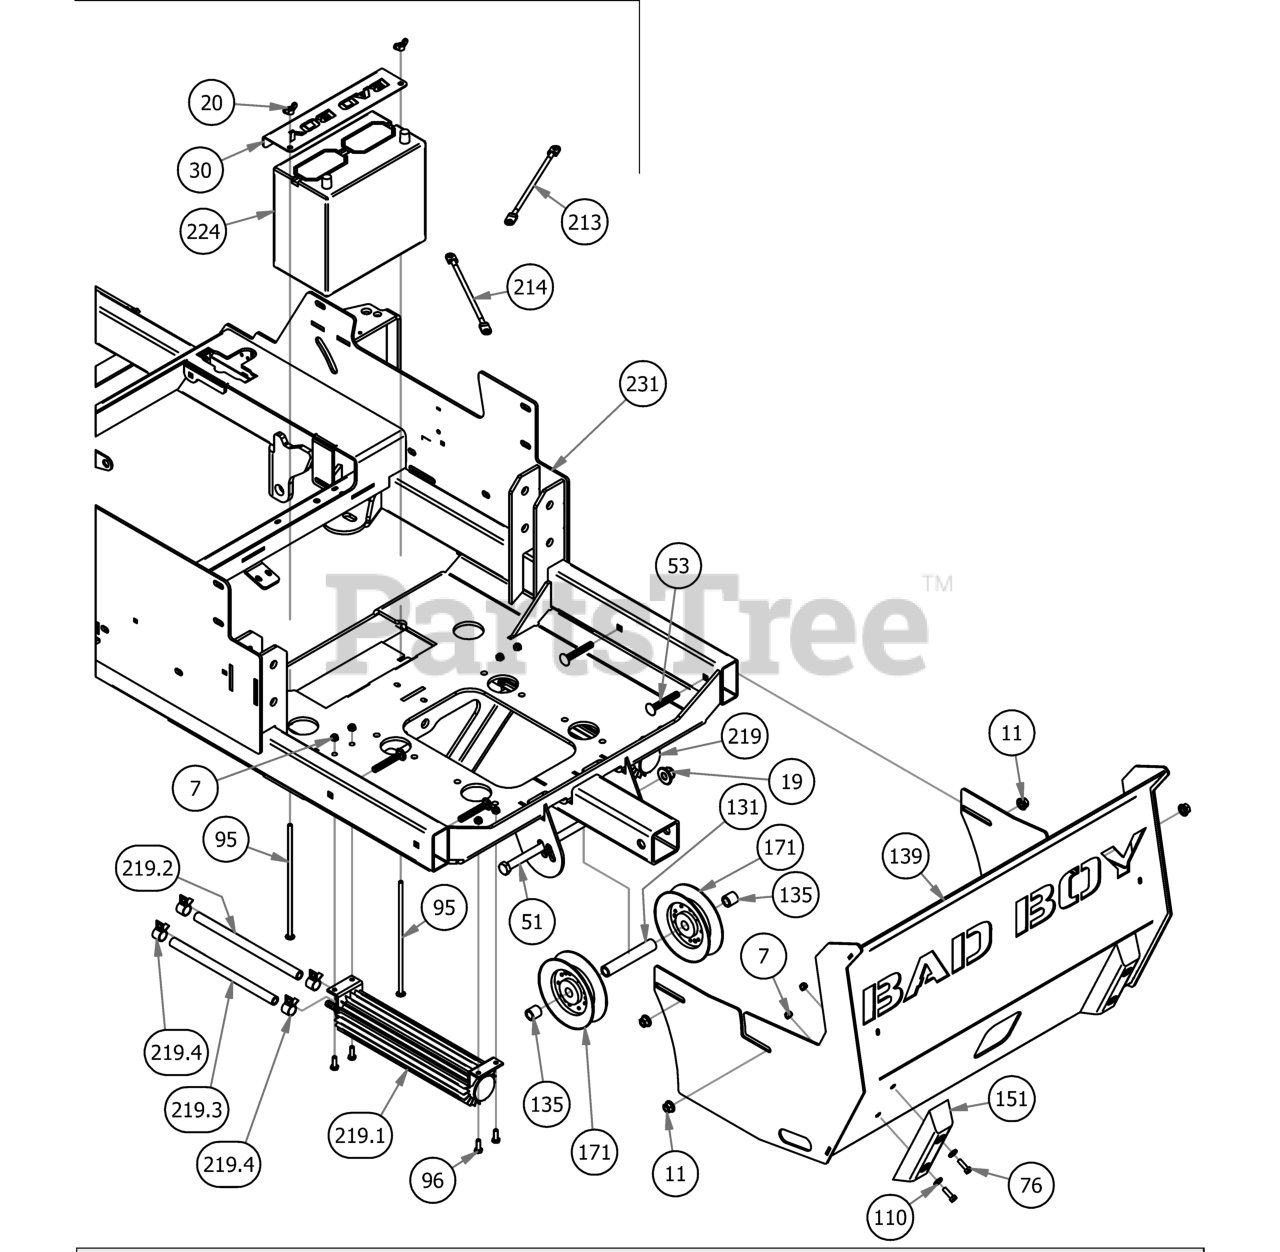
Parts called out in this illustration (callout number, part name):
7	1/4-20 Hex flang lock nut
11	3/8-16 NYLON INSERT FLANGE LOCKNUT (GR.F) ZINC
19	1/2-13 NYLON INSERT FLANGE LOCKNUT ZINC
20	1/4" Wing Nut
30	2019 Horizontal Battery Hold Down Cover
51	1/2" x 8 1/2 GR 5 Hex Bolt
53	3/8" x 2 1/2" Carriage Bolt
76	1/4-20 x 1-1/4 GR 5 Hex Bolt
95	1/4" x 1" Carriage Bolt
96	1/4" x 3/4" Hex Bolt
110	1/4" Flat Washer
131	2019 Pulley Spacer .75 x .5 x 4.375
135	Spacer 3/4 OD x 1/2 ID x 3\4 Length
139	2019 Horizontal Suspension Rear Cover
151	8" Rubber Bumper
171	2019 Outlaw Horizontal Rear V Pulley
213	Red Battery Cable - Diesel
214	Black Battery Cable - Diesel
219	Renegade Oil Cooler Assembly
219.1	2019 12" Oil Cooler With Fittings
219.2	3/8" Clear Hose
219.3	3/8" Clear Hose
219.4	3/8" Hose Clamp
224	Battery - Diesel/Renegade Models PF-516
231	2019 Horizontal Diesel Frame
